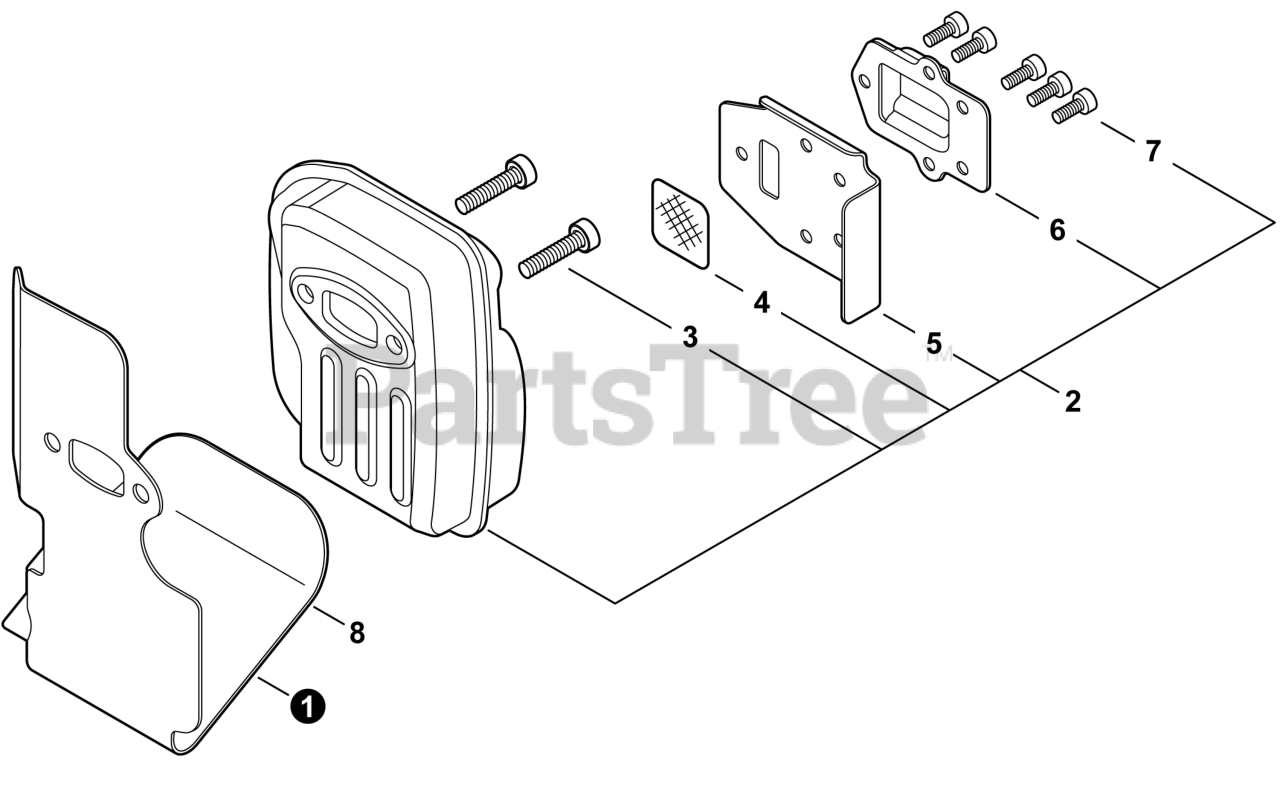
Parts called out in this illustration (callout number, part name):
1	HEAT SHIELD, EXHAUST
2	MUFFLER ASSY
3	BOLT, TORX 5x16
4	SCREEN, SPARK ARRESTER
5	GASKET, EXHAUST
6	GUIDE, EXHAUST
7	BOLT, TORX 4x8
8	GASKET KIT: ENGINE, INTAKE, EXHAUST
